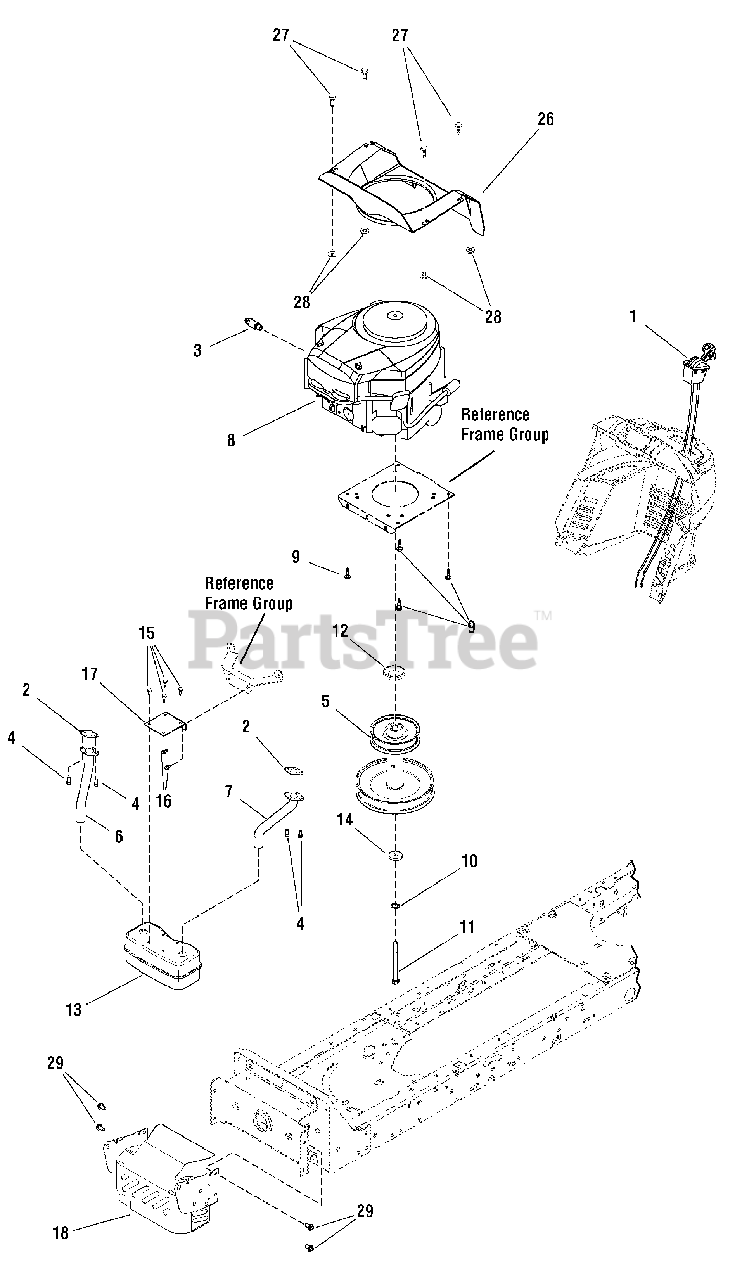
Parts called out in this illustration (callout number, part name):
1	CONTROL, Throttle Double
2	GASKET, Exhaust
3	OIL VALVE ASSEMBLY
4	CAPSCREW, 5/16-18 x 3/4
5	STACK PULLEY ASSEMBLY
6	TUBE, Exhaust, Right
7	TUBE, Exhaust, Left
8	* Engine, 23HP B&S Mod. 44L777-0130-G1
9	SCREW, Self Tap, 3/8-16 x 1-1/4
10	WASHER, Star
11	BOLT, Hex 7/16-20 x 1-1/2
12	SPACER, Engine
13	MUFFLER, Twin
14	WASHER, Flat, 1
15	BOLT, 1/4-14 x 3/8
16	SCREW, Hex, 1/4-20 x 5/8
17	BRACKET, Muffler
18	HEAT SHIELD
26	AIR DUCT, Plenum
27	SCREW, Hex Flange, 1/4-20 x 5/8
28	NUT, Hex Flange, 1/4-20
29	CAPSCREW, Hex Head, 5/16-18 x 3/4
